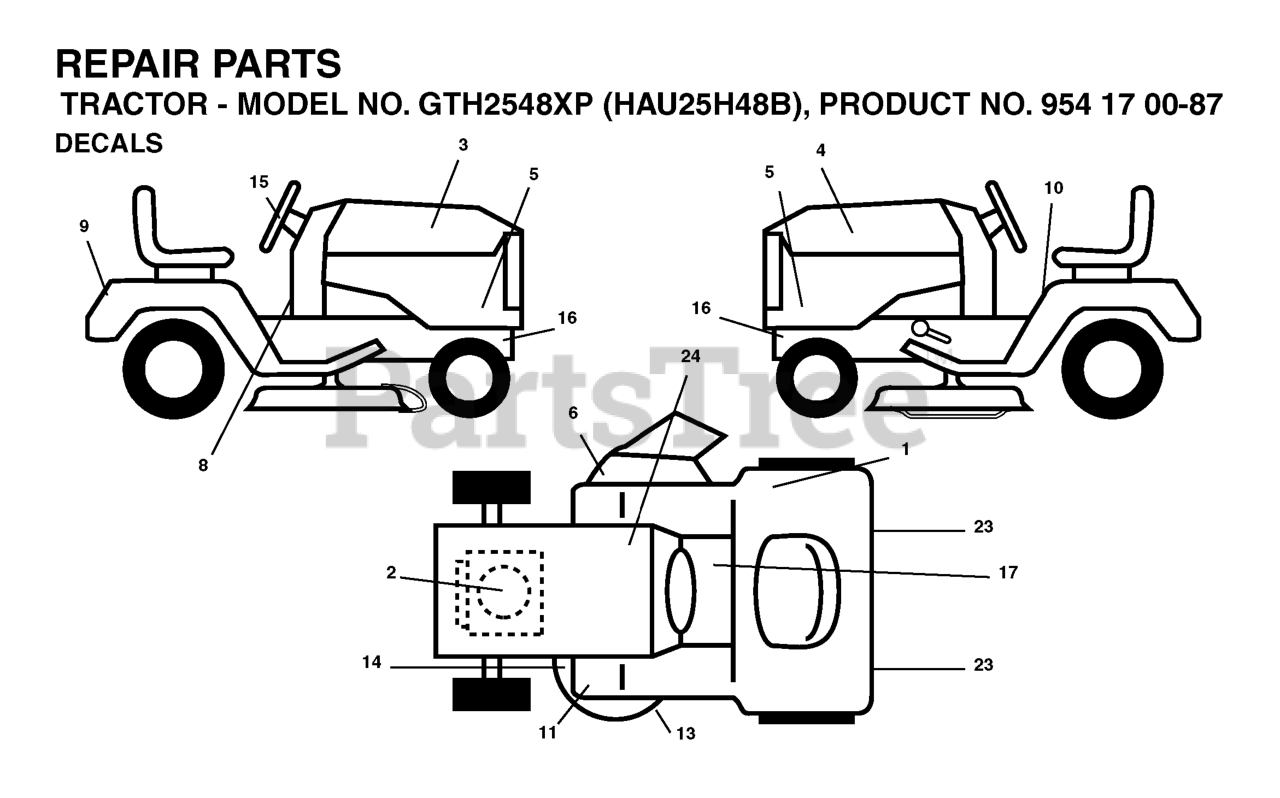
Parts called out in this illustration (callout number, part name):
1	DECAL
2	DECAL.ENG.25HP.KAWA.HSQV.XP
3	RH HOOD DECAL
4	LH HOOD DECAL
5	DECAL HOOD SIDES
6	DECAL.INTERNATIONL.CUTFINGER
8	DECAL, DASH
9	DECAL, FENDER
10	DECAL READ OWNER'S MAN SYMS
11	DECAL, FOOTREST
13	DECAL V-BELT SCHEMATIC
14	DECAL CLUTCH/BRAKE
15	DECAL.WHEEL.STEERING.HUSQ.PERM
17	DECAL PARK BRAKE
23	REFLECTOR-TAIL YT
24	DECAL BTRY SYMBOLS
